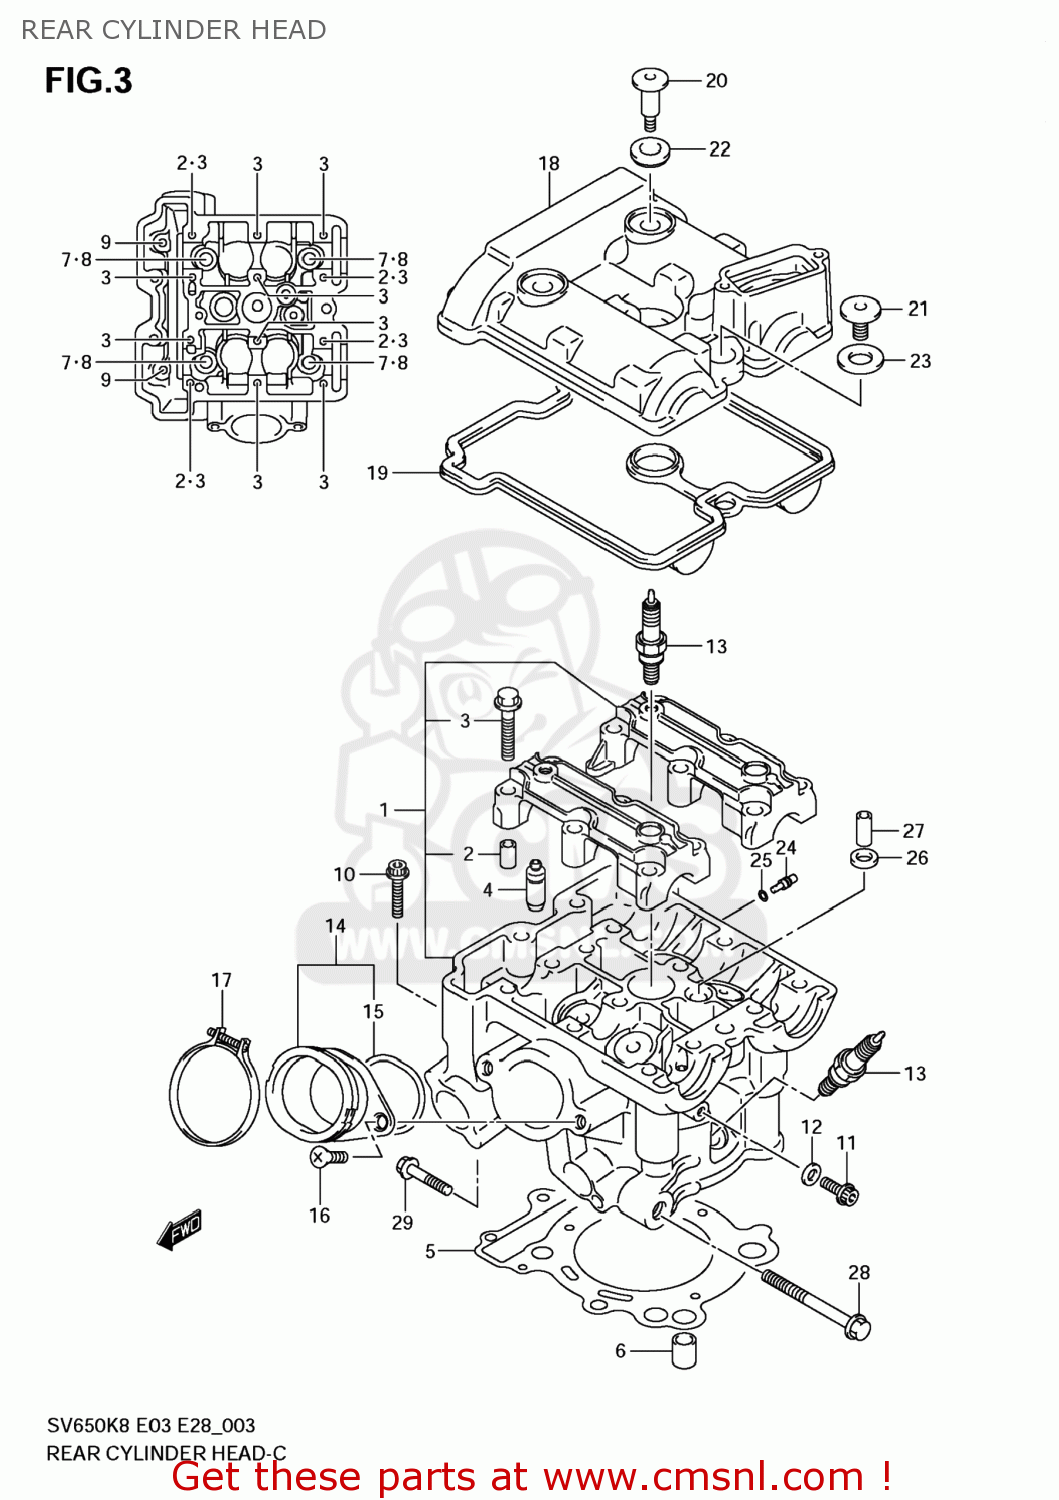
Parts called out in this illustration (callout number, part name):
1	HEAD ASSY,CYLINDER RR
2	PIN(6.2X8X11)
3	BOLT(6X39)
4	GUIDE,VALVE
5	GASKET,CYLINDER HEAD (NAS)
6	PIN
7	WASHER(10.5X19X2)
8	BOLT(10X160)
9	BOLT(6X70)
10	BOLT
11	BOLT
12	GASKET(5.8X13X1.2) (NAS)
13	PLUG,SPARK(CR8E)
14	PIPE ASSY,INTAKE RR
15	O RING(D:2.4,ID:47X42)
16	SCREW
17	CLAMP
18	COVER,CYLINDER HEAD RR
19	GASKET,CYLINDER HEAD COVER (NAS)
20	BOLT(7X17.5)
21	BOLT(7X31)
22	WASHER,CYL HEAD COVER
23	CUSHION,HEAD COVER BOLT
24	JET(8)
25	O RING(D:1.2,ID:4)
26	GASKET,2ND AIR PASSAGE (NAS)
27	PIN(6.2X8X16)
28	BOLT(10X110)
29	BOLT
